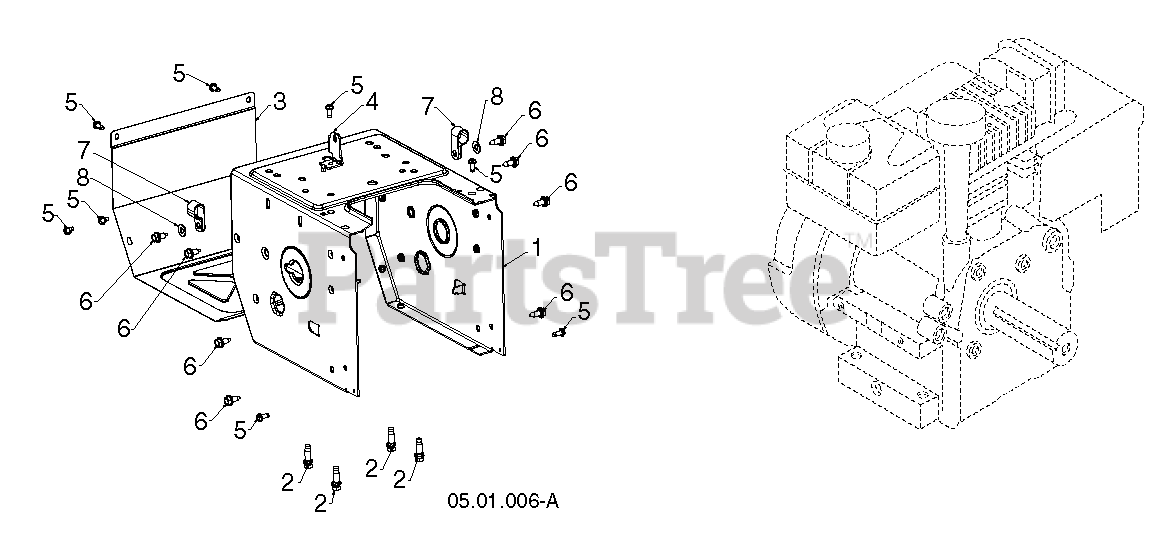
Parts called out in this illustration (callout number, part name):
1	FRAME.GEAR.CASE.SNOW.BLACK
2	BOLT 3/8-16X1-1/8
3	Snow Frame Cover, Black
4	BRACKET.SHIFTER.BZP
5	SCREW 14-20 X 5/8
6	BOLT.HEX.HD.WASHER.5/16-18X.75
7	CLIP.CABLE.BLK
8	WASHER.FLAT.343X.750X16 GA BLK
